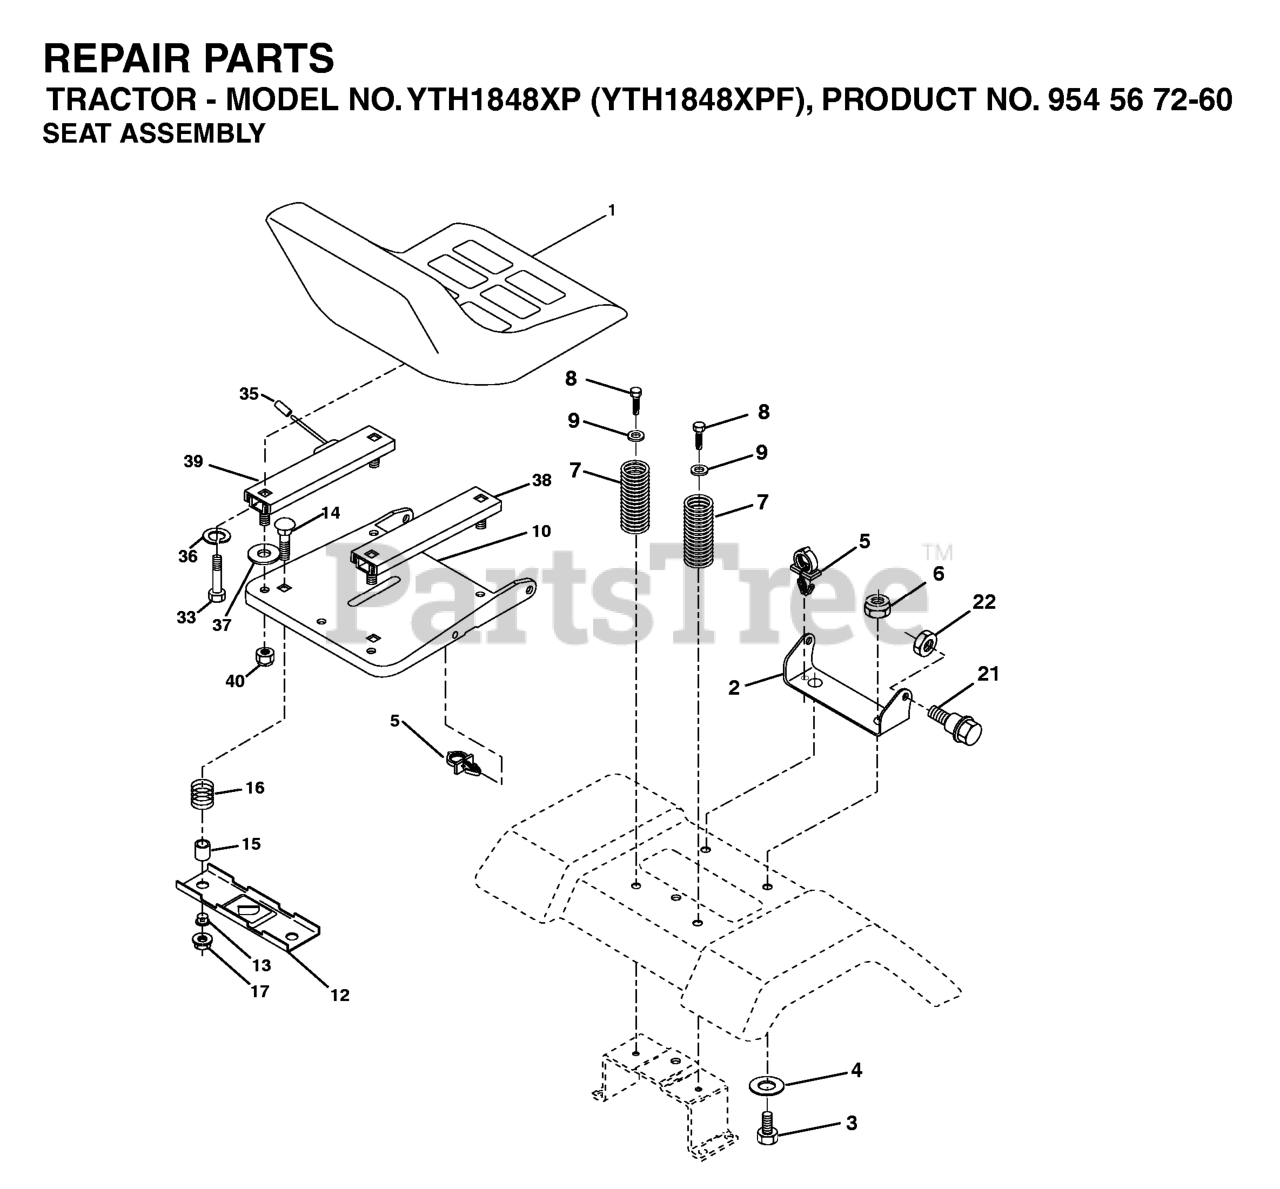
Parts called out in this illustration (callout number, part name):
1	SEAT
2	SEAT PIVOT BRKT
3	BOLT, HEX 3/8-16X1
6	NUT
7	SPRING COMPRESSION
8	SCREW 3/8-16X1
9	WASHER
10	PAN SEAT
12	BRKT SWITCH
14	BOLT.ROUND.HEAD.SQUARE.NECK
15	SPACER SPLIT
16	SPRING COMPRESSED
17	NUT T
21	BOLT.SHOULDER.5/16-18
22	NUT.71038.31-18.HEX.NYLOCK
33	BOLT.FIN.HEX.5/16-18X3/4
38	TRACK SLIDE, SEAT(R)
39	TRACK SLIDE, SEAT(L)
40	LOCKNUT
